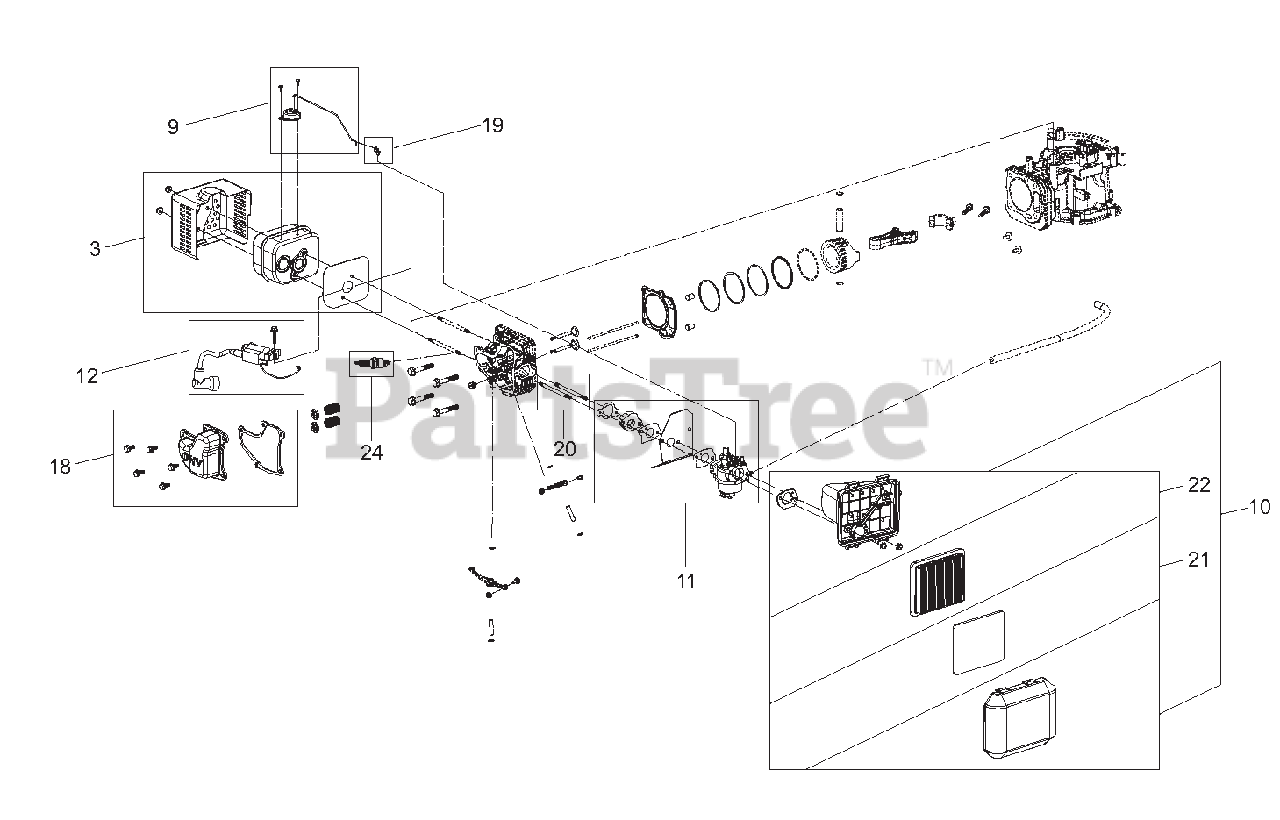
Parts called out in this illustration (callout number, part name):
1	KIT, AIR VANE CHOKE - SVC
2	KIT, GOVERNOR ARM - SVC
3	KIT, MUFFLER AND SHIELD - SVC
4	KIT, FLYWHEEL AND FAN - SVC
5	KIT, BRAKE ASM RECOIL - SVC
6	KIT, E-START BRAKE ASM - SVC
7	KIT, ARIENS STYLE - SVC
8	KIT, FLYWHEEL SHIELD - SVC
9	KIT, THERMAL CHOKE CONTROL-SVC
10	KIT, AIR CLEANER ASM - SVC
11	KIT, CARBURETOR COMPLETE - SVC
12	KIT, IGNITION COIL - SVC
13	KIT, SEAL AND GASKET - SVC
14	KIT, FLYWHEEL AND FAN - SVC
16	KIT, STARTER - SVC
17	KIT, WIRE HARNESS - SVC
18	KIT, VALVE COVER - SVC
19	LOCK, THROTTLE - SVC
20	STUD, INTAKE - SVC
21	ELEMENT, AIR CLEANER
22	FILTER, AIR - LONCIN 160CC
23	KIT, FUEL LINE W/FILTER - SVC
24	SPARK PLUG, LONCIN 160CC
25	DIPSTICK, OIL - SVC
26	CAP, FUEL - SVC
27	ASM, FUEL TANK W/HARDWARE
28	KIT, RECOIL - SVC
29	ENGINE,SERVICE,AC SERIES
29	ENGINE,SERVICE,AC SERIES,ELEC
